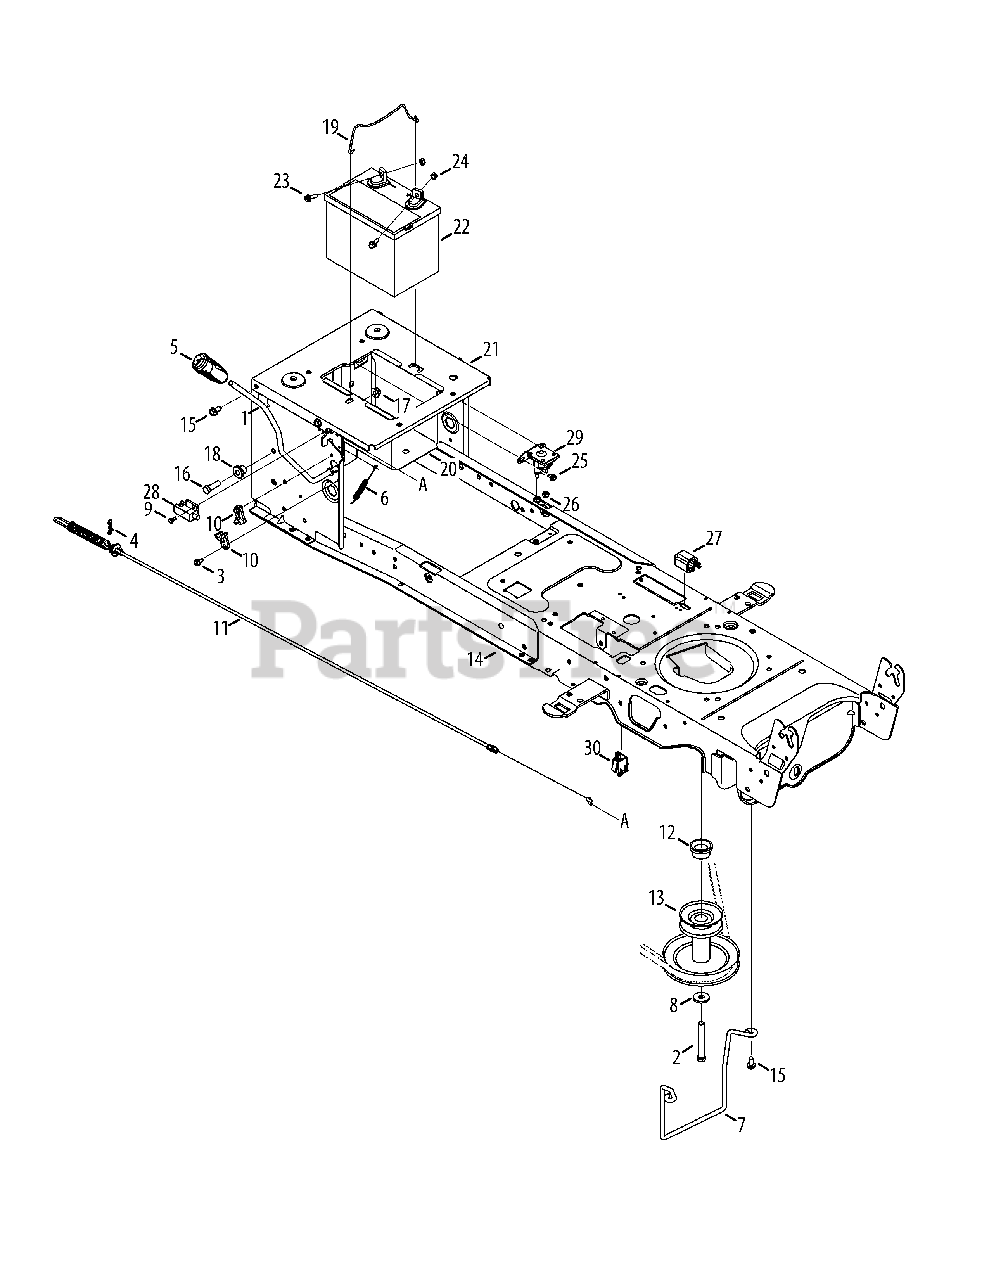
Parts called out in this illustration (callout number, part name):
1	Handle Ass’y, PTO
2	Hex Screw, 7/16-20, 3.50, Gr5, Lock
3	Screw, Self-tapping, 1/4-20, 0.50
4	Pin, Cotter, Bow-Tie 72
5	Grip, Handle, 3/8
6	Spring, Ext, .38 Dia x 5.6
7	Belt Keeper Rod
8	Washer, Flat, .450 x 1.250 x .164
9	Screw, Shoulder, #10-32, .500
10	Bearing, PTO
11	Cable, Engag, Deck
12	Spacer, 1.010 x 1.400 x .825
13	Pulley, Engine, 3.56 x 6.12 Dia.
14	Frame Ass’y, Lower
15	Screw, Self-tapping, 5/16-18, .750,
16	Hex Screw, 3/8-16, 1.25, Gr5, Std
17	Nut, Flange Lock, 3/8-16, Grf,
18	Spacer, Shoulder, .38 x 1.0 x .70
19	Rod, Battery
20	Tray, Battery
21	Bracket, Frame, Seat
22	Battery
23	Hex Flange Screw, 1/4-20, .75, Gr5
24	Nut, Sems, 1/4-20
25	Screw, Self-tapping, 1/4-20, 0.375,
26	Nut, Flange Lock, 1/4-20, Grf,
27	Switch, 3-Pole
28	Switch, Interlock
29	Solenoid, 12V
30	Switch, Plunger, Snap Mount
